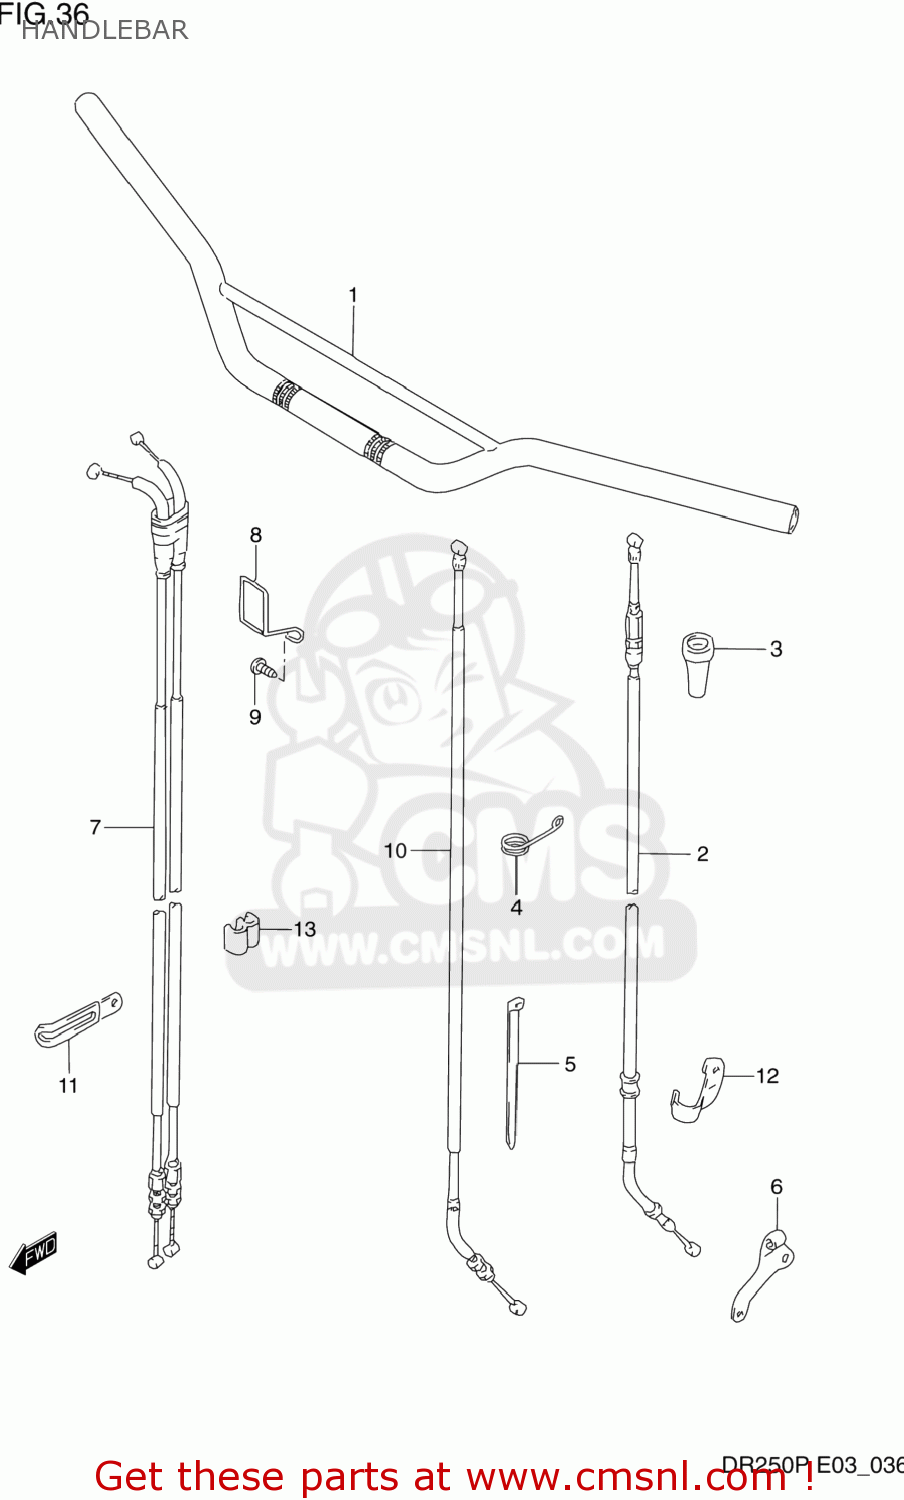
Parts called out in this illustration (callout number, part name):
1	HANDLEBAR
2	CABLE ASSEMBLY,CLUTCH
3	BOOT,CLUTCH CABLE
4	GUIDE,CLUTCH CABLE
5	CLAMP(L:100)
6	STOPPER,CLUTCH CABLE
7	CABLE SET,THROTTLE
8	GUIDE,CABLE
9	SCREW
10	CABLE ASSY,DECOMP
11	CLAMP
12	CLAMP,CLUTCH CABLE
13	CLIP
